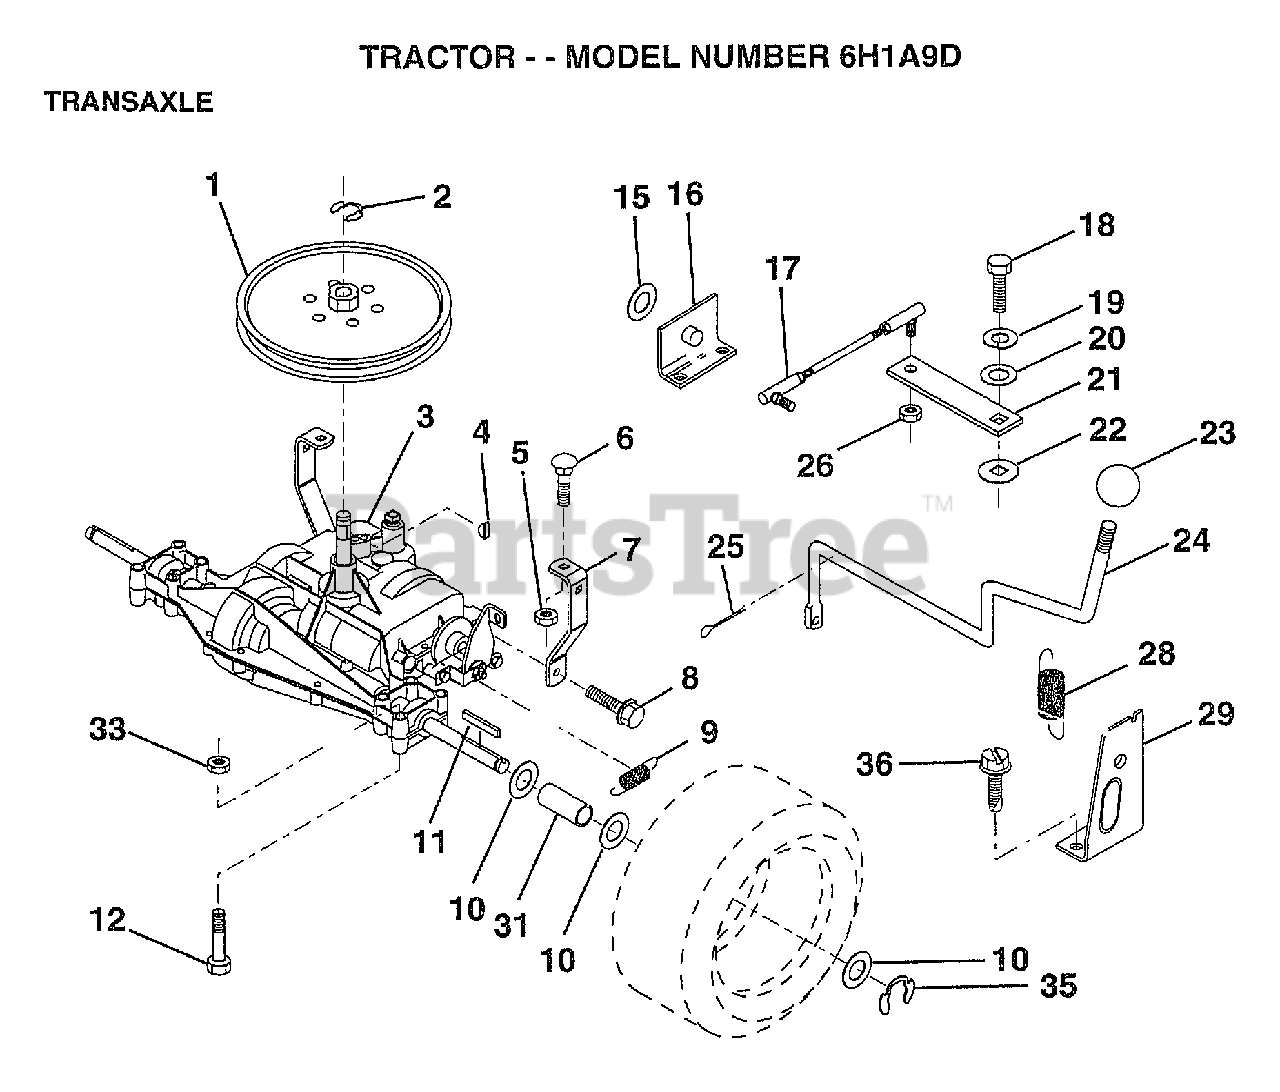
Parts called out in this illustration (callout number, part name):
1	PULLEY
6	BOLT
7	"STRAP,TORQUE"
8	SCREW
9	SPRING.BRAKE.RETU
10	WASHER
11	SQUARE KEY
12	BOLT
16	"SUPT,HDLE SHT LH"
17	"LINK,SHIFT"
18	BOLT.1/4-28.W/PAT
19	LOCKWASHER
20	WASHER LT
21	"ARM,SHIFT"
22	WASH-SHFT PLT LT
23	KNOB.DUCKHEAD.1/2
24	"ROD,SHIFT"
25	PIN COTTER 1/8
26	NUT.LOCK.5/16-24
28	"SPRING,EXT"
29	"SUPT,HDLE RH"
31	SPACER LT
35	E-RING LT
36	SCREW
